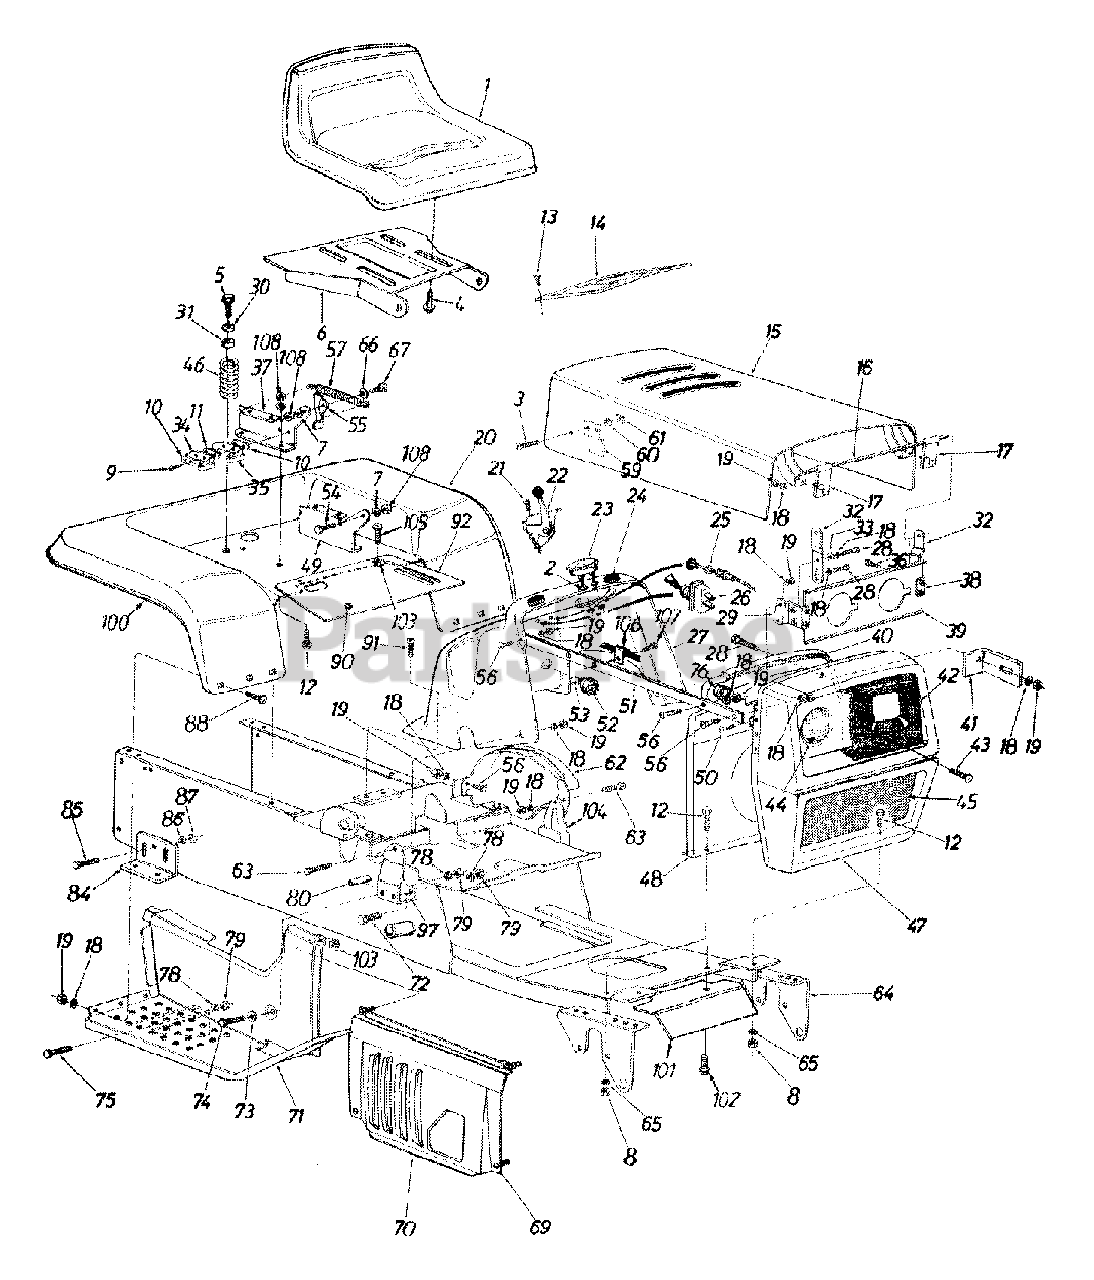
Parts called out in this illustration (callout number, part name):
1	Seat Ass'y.
2	L-Wash. .190" I.D.
3	Truss Hd. Mach. Scr. #10-24 x .38" Lg.
4	Hex Wash. Hd. Self-Tap Scr. 3/8-16 x .62" Lg. (Gr. 5)
5	Hex Wash. Hd. Tap Scr. 5/16-18 x .75" Lg.
7	L-Wash. 5/16" I.D.
8	Hex Nut 5/16-18 Thd.
9	Hex Wash. Hd. AB-Tap Scr. #8 x .5" Lg.
10	Insulator Plate
11	Insulator Boss Plate
12	Hex Bolt 5/16-18 x .75" Lg.
13	Self-Tap Oval Hd. Scr. 1/2" Lg.
14	Dash Panel Cover
15	Hood Ass'y.
16	Hinge Rod
17	Hood Hinge Ass'y.
18	Bell-Wash. 1/4" I.D.
19	Hex Nut 1/4-20 Thd.
20	Fender w/Taillight Hole
21	Fl-C-Sunk Hd. Tap Scr.
22	Throttle Control
23	Ammeter
24	Rubber Bumper
25	Choke Control
26	Light Switch
27	Dash Panel
28	Hex Bolt 1/4-20 x .62" Lg.
29	Hood Support Brkt. Ass'y. - R.H.
30	Fl-Wash. .344" I.D. x .875"
31	Bushing
34	Safety Switch (Seat)
35	Safety Switch (Seat)
36	Hex Bolt 1/4-20 x .38" Lg.
37	Seat Pivot Support Brkt. - R.H.
38	Hood Support Brkt. Ass'y. - L.H.
41	Heat Shield Brkt.
42	Head Lamp Bezel
43	Truss Mach. Scr. #10-24 x .50" Lg.
44	Head Lamp
45	Grille Screen
46	Compression Spring 4.5" Lg.
47	Grille
50	Truss Mach. Scr. 1/4-20 x .75" Lg.
53	Ignition Key
54	Shld. Bolt .437" Dia. x .162"
55	Seat Lift Bracket
56	Hex Bolt 1/4-20 x .75" Lg.
57	Extension Spring 5.31" Lg.
59	Hood Spring
60	L-Wash. #10
61	Hex Nut #10-24 Thd.
62	Speed Control Guide
63	Truss Mach. Scr. 1/4-20 x .75" Lg.
66	Spr. Wash. .445" I.D. x .75"
67	Shld. Bolt .437" Dia. x .268"
69	Truss Mach. Scr. #10-24 x .5" Lg.
70	Side Panel - R.H.
70	Side Panel - L.H.
71	Foot Step Panel Ass'y. - R.H.
71	Foot Step Panel Ass'y. - L.H.
72	Hex Bolt 3/8-16 x 1.00" Lg. Grade 5
73	Fl-Wash. .385" I.D. x .62" O.D.
74	Hex Bolt 3/8-16 x 3.00" Lg.
75	Hex Bolt 3/8-16 x 1.00" Lg. Grade 5
76	Snap Bushing
78	L-Wash. 3/8" I.D.
79	Hex Nut 3/8-16 Thd.
80	Spacer .375" I.D. x .62" O.D. x 2.00" Lg.
84	Transaxle Support Brkt.
85	Rd. Hd. Rib Neck Scr. 3/8-24
86	L-Wash. 3/8" I.D.
87	Hex Nut 3/8-24 Thd. (Gr. 5)
88	Carr. Bolt 1/4-20 x .50" Lg.
90	Snap Bushing
91	Hex Wash. Hd. Tap Scr. 1/4-20 x .5" Lg.
103	Speed Nut #10-24 Thd.
104	Dash Panel Mtg. Brkt. - L.H.
105	Truss Mach. Scr. #10-24 x .5" Lg.
106	Clamp
107	Self-Tap Scr. 5/16 x .5" Lg.
108	Hex Nut 5/16-18 Thd. (Gr. 5)
